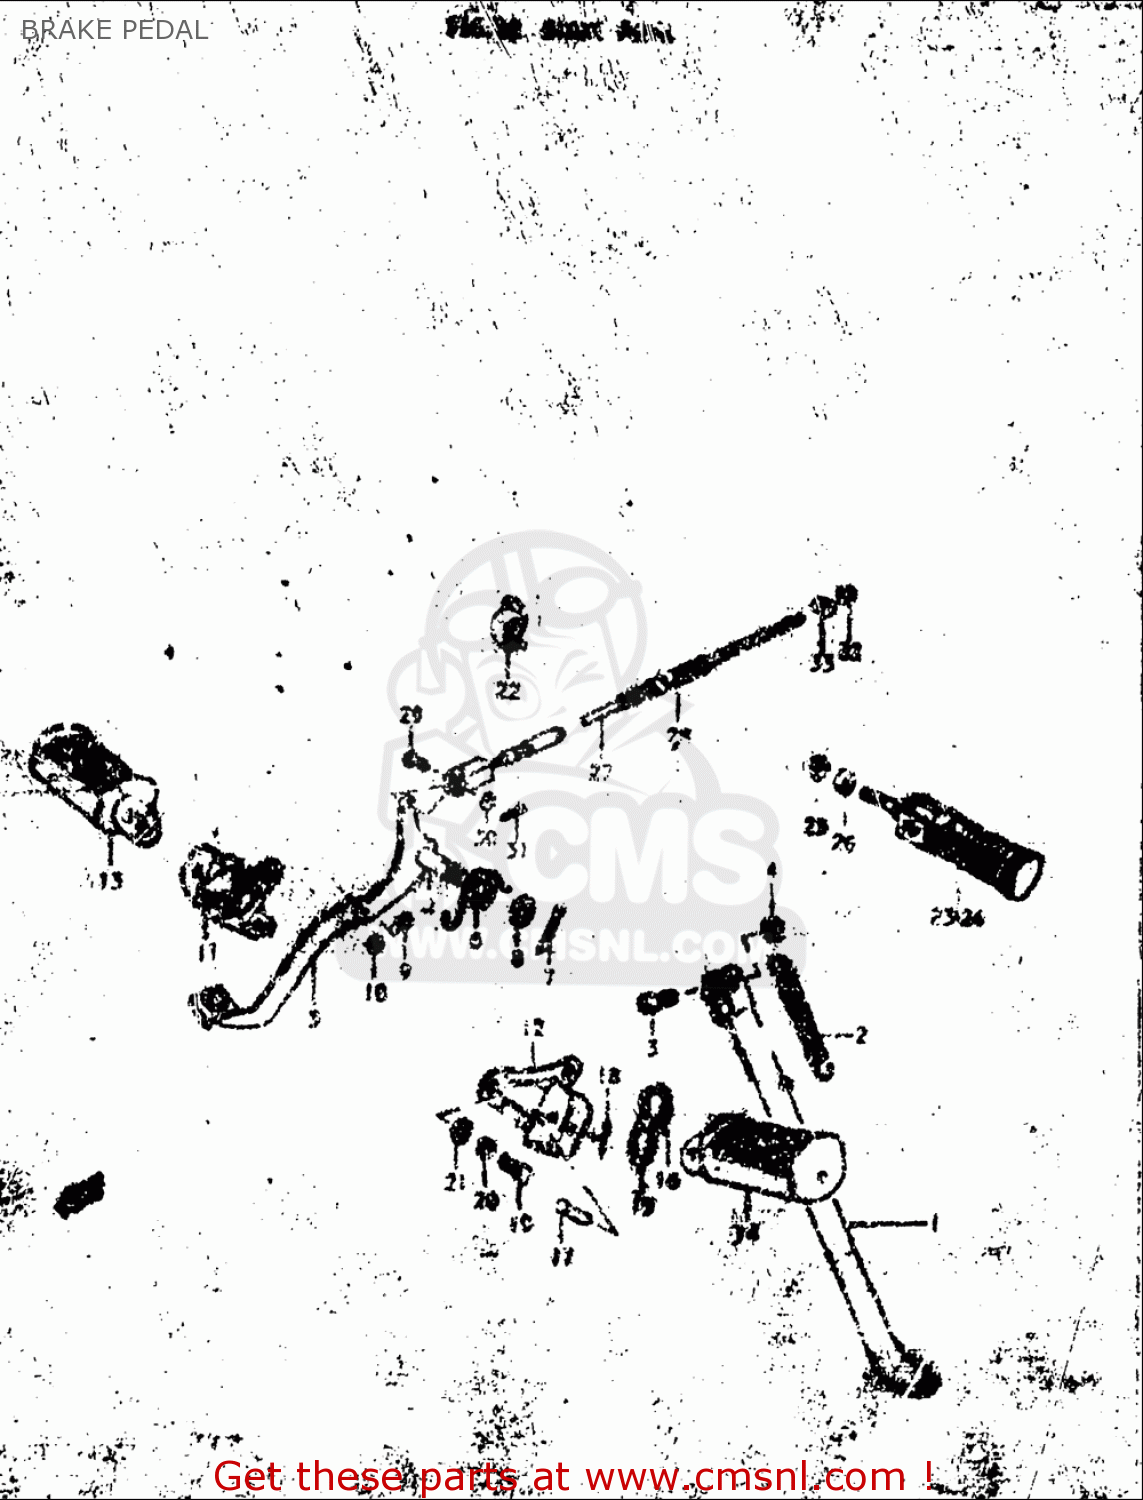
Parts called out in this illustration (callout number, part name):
2	SPRING
3	BOLT(10X30)
4	NUT
6	SPRING
8	WASHER(15.5X26X2.3)
9	BOLT
10	NUT
15	WASHER(22.5X38X1)
16	WASHER
17	PIN
18	PIN
19	BOLT
20	WASHER,LOCK
21	WASHER
24	FOOTREST ASSY,PILLION
25	WASHER,LOCK
27	CABLE,RR BRAKE
29	PIN(L:17.5)
30	WASHER
31	PIN
32	NUT
33	PIN(11X18)
